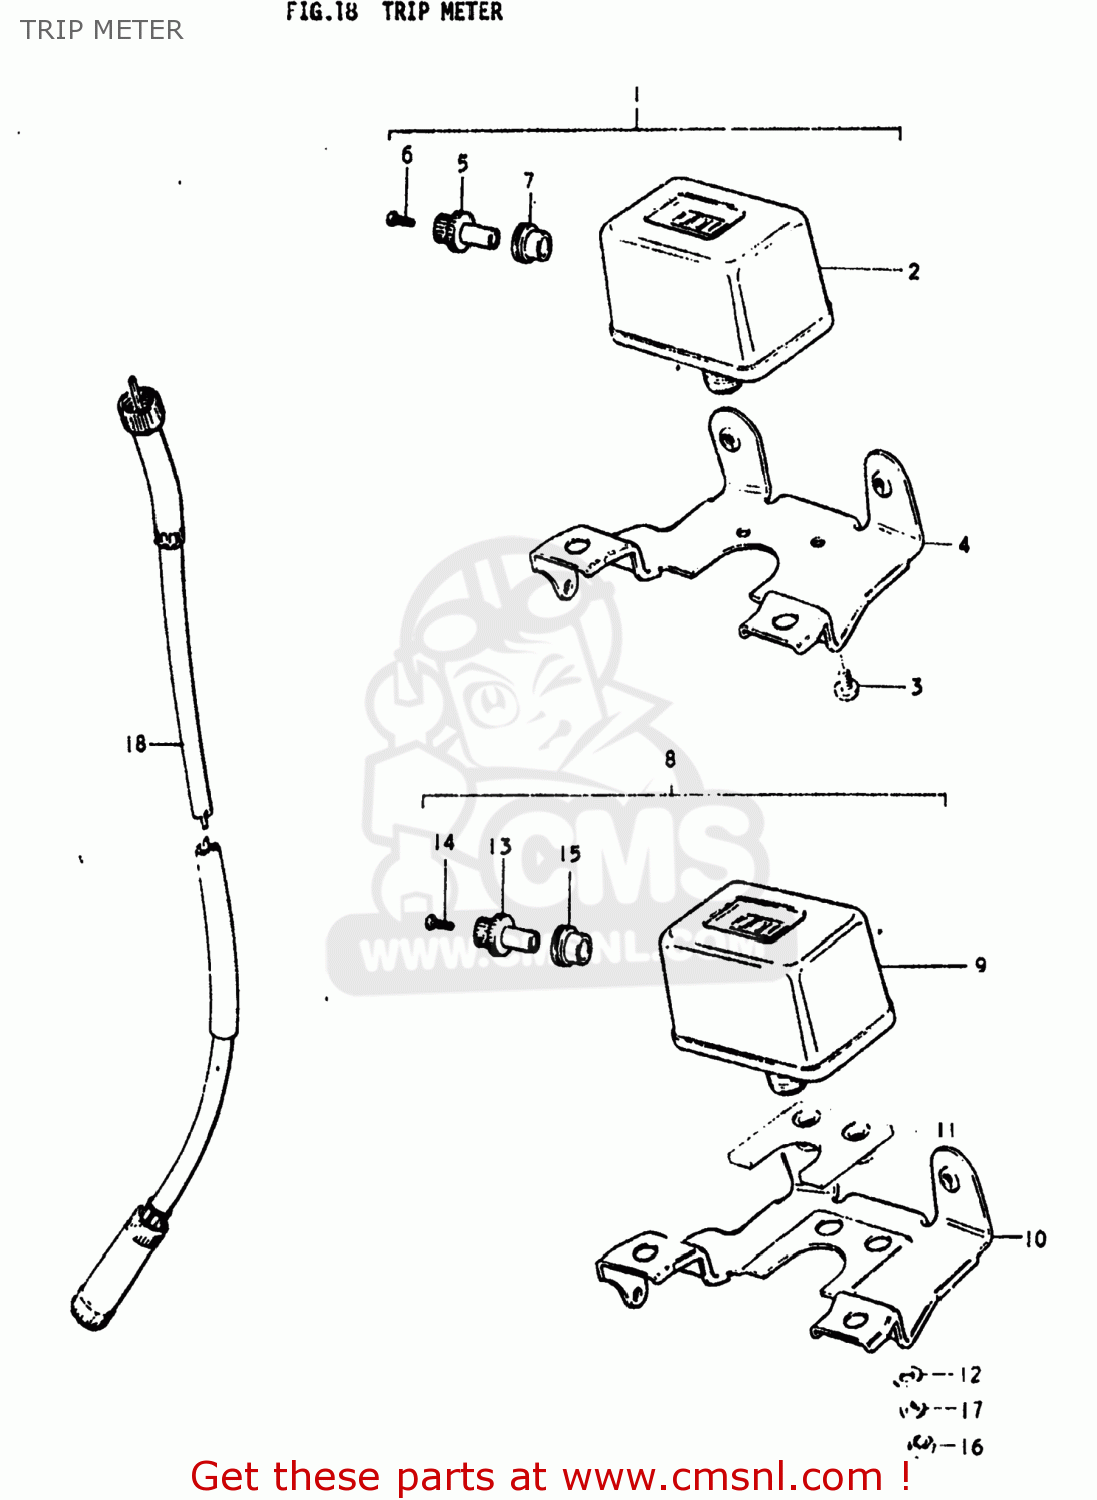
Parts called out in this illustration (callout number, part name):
1	ODOMETER ASSEMBLY
2	TRIP METER
3	SCREW
4	BRACKET,TRIPMETER
6	SCREW
7	COVER,TRIPMETER KNOB
8	ODOMETER ASSEMBLY
9	TRIP METER
10	BRACKET,TRIPMETER
11	CUSHION,TRIPMETER
12	WASHER,METER
14	SCREW
15	COVER,TRIPMETER KNOB
16	NUT
17	LOCK WASHER
18	CABLE ASSEMBLY,SPEEDOMETER
